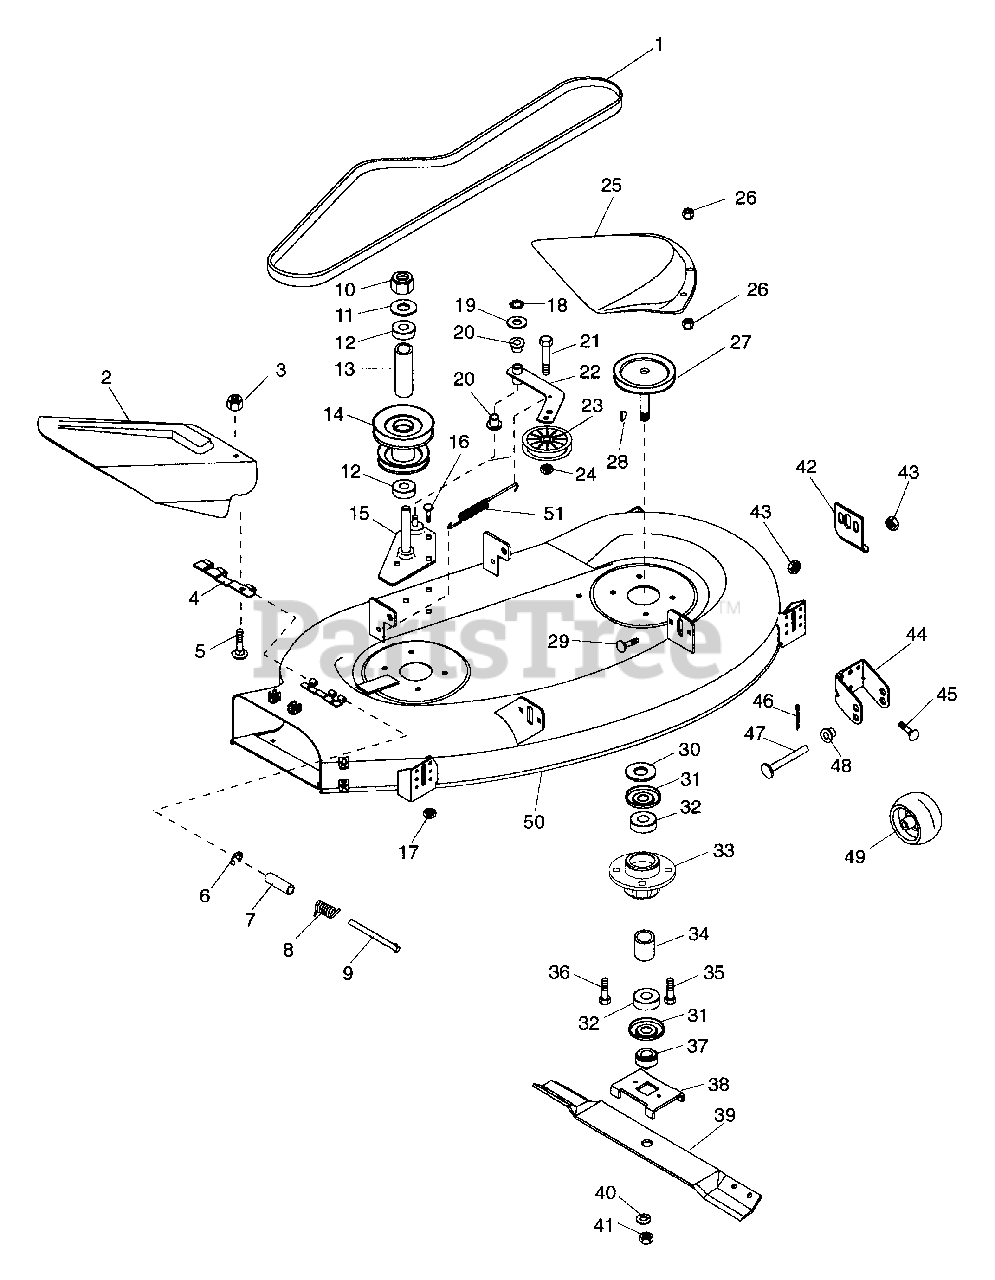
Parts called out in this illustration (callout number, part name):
1	V-BELT, 4L-WRAPPED
2	40IN. CHUTE DEFLECTOR
3	NUT-LK-FLG .250-20 PL
4	HINGE PLATE
5	BLT-RDHDSQNK .25-20X.50 SHT PL
6	RG-RTNG-EXT .312X.025
7	BSHG-SLV .334 X .502 X 1.437
8	SG-TORS .095X.50X 1.0
10	NUT-LK-NYL.625-18 PL
11	WSHR-FL-STL .640X1.005X.062 PL
12	BRG-BALL .625X1.375X.44
13	SPACER .640X.880X2.545
14	JACKSHAFT PULLEY
15	MOUNT PLATE 40"
16	BLT-RDHDSQNK .312-18X.62SHTPL
17	NUT-FLG. .312-18 PL
18	RG-RTNG-EXT .500X.042 (E)
19	WSHR-FL-STL .505X.880X.072 PL
20	BSHG-FLG .500X.625X.187X.750FD
21	BLT-HEX .38-16X1.50 PL GR5
22	IDLER ARM
23	IDLER-FLAT 3.00X.38
24	NUT-LK TOP .375-16 GR C YWZC
26	NUT-LK-CTR .375-16 GR A PL
27	L. SPINDLE SHEAVE
27	R. SPINDLE SHEAVE
28	KEY-WDRF .188X.625X.31 SAE9MOD
29	BLT-RDHDSQNK.31-18X.75GR5SHTPL
30	WSHR-FL-STL .755X1.250X.125
31	BEARING SLINGER
32	BRG-BALL .750X1.781X.61
33	SPINDLE HOUSING
34	SPACER .753X1.000X1.140
35	BLT-RDHDSQNK .38-16X1.0 PL
36	BLT-HEX .38-16X1.00 PL GR5
37	RETAINER HUB
38	BLADE TRAY 48
40	WSHR-LK .750X.188 MED PL
41	NUT-JAM .75-10 PL
42	MOWER ADJUSTMENT TAB
43	NUT-FLG. .312-18 PL
44	ROLLER CLEVIS
45	BLT-RDHDSQNK .312-18X.62SHTPL
46	PIN-COTR .15 X 1.0 PL
47	PIN-CLEV .371X3.25 YWZC
48	BSHG-FLG .372X.500X.312X.625NY
50	40" MOWER DECK W/DECALS
50	40" MOWER DECK ASSY COMPLETE
51	SG-TENS .113X.812X7.00
